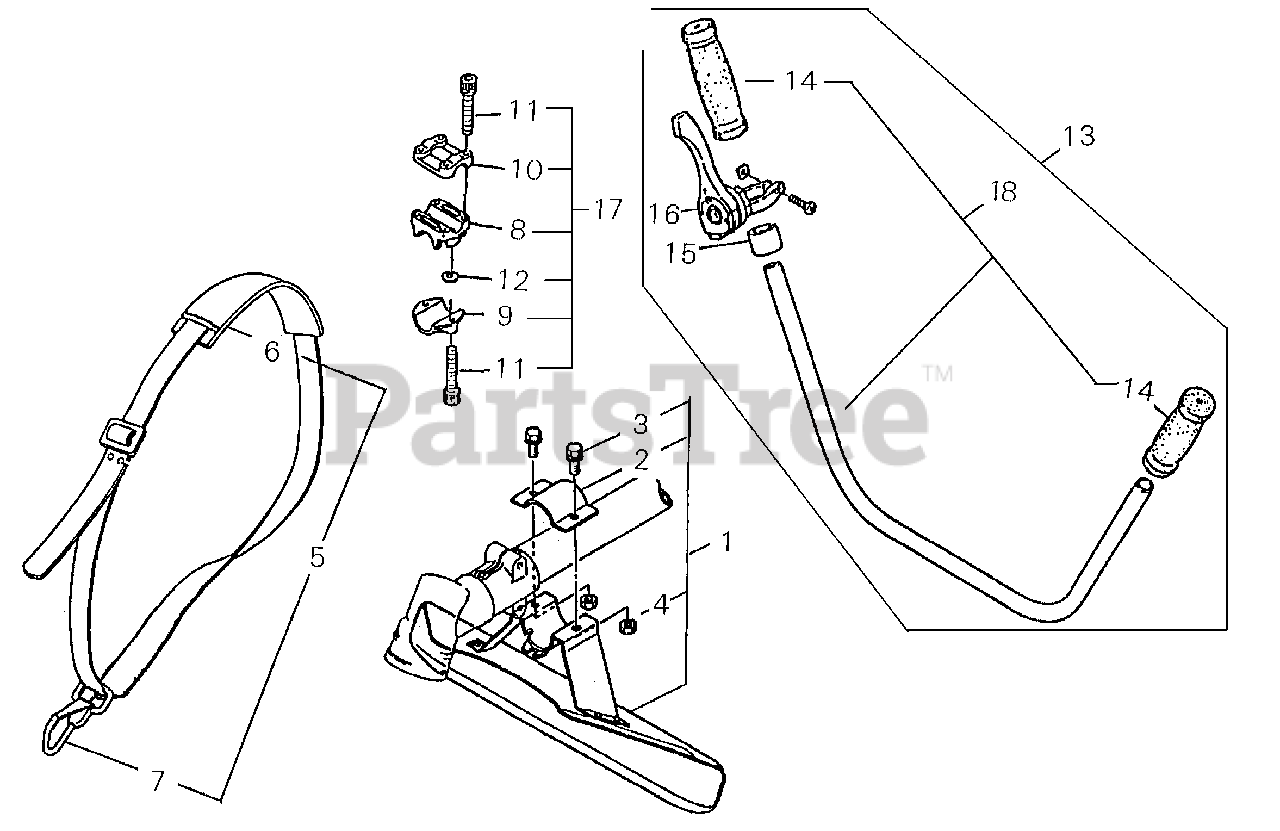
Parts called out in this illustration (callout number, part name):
1	DEBRIS SHIELD ASSY
2	CLAMP, UPPER
3	BOLT M5×12
4	NUT M5
5	HARNESS ASSY
6	PAD, SHOULDER
7	HOOK, SNAP
8	BRACKET, HANDLE
9	CLAMP, LOWER
10	BRACKET, UPPER
11	BOLT M5×25
12	WASHER, FLAT 5.5×10×0.8
13	HANDLEBAR ASSY, W/ THROTTLE
14	GRIP
15	COLLAR
16	LEVER, THROTTLE
17	BRACKET ASSY, HANDLE
18	HANDLEBAR ASSY
